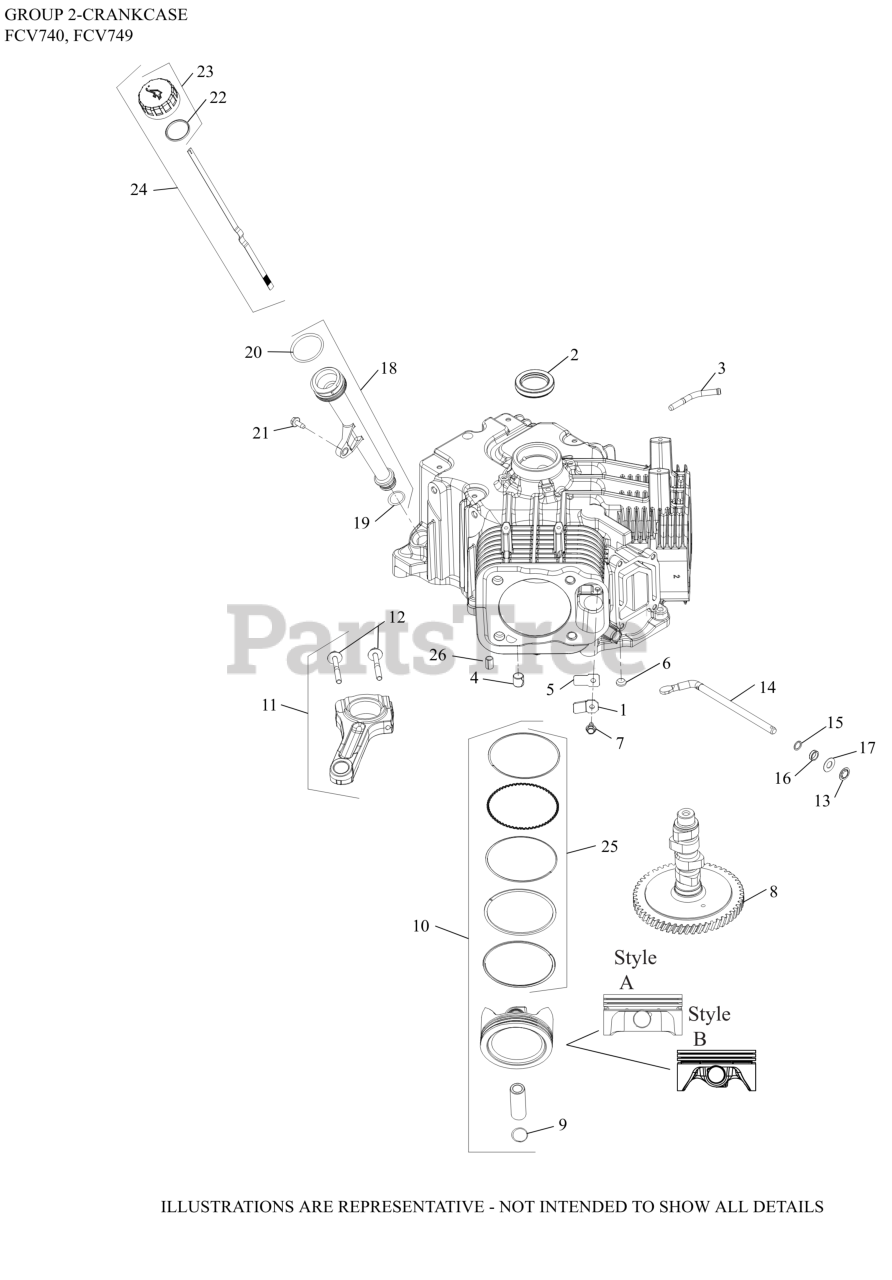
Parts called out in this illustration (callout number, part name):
1	RETAINER, BREATHER REED
2	SEAL, OIL (HELIX LIP)
4	PIN, LOCATING
5	REED, BREATHER-(#2440207S)
6	PLUG, CUP
7	SCREW, FLG THD FRM M5X.8X10
8	KIT, CAMSHAFT
9	RETAINER, PISTON PIN
10	KIT,PSTN/RNG STYLE A(STD)(#2587406S)
10	KIT,PSTN/RNG STYLE A(.08)
10	KIT,PSTN/RNG STYLE A(.25)USE 2587411-S
10	KIT,PSTN/RNG STYLE A(.50)(#2587404S)
10	KIT,PSTN/RNG STYLE B(STD)
10	KIT,PSTN/RNG STYLE B(.08)
10	KIT,PSTN/RNG STYLE B(.25)
10	KIT,PSTN/RNG STYLE B(.50)
12	KIT, ROD BOLTS-(#25086677S)
13	RETAINER, RING
14	SHAFT, GOVERNOR CROSS
15	WASHER, FLAT 11/32"
16	SEAL, GOVERNOR CROSS SHAFT
17	WASHER, FLAT 9 MM
18	TUBE ASSEMBLY
19	O-RING, LOWER OIL FILL TUBE
20	O-RING, UPPER OIL FILL TUBE
21	SCREW, FLG THD FRM M5X0.8X13
22	O-RING, DIPSTICK
23	KIT, OIL FILL CAP (YELLOW)
24	DIPSTICK, ASSY
25	RING DISC USE PISTON ASSY PER SPEC
25	RING SET(.08)STYLE A-1.5mm Tp RING THICK
25	RING SET(.25)STYLE A-1.5mm Tp RING THICK
25	RING SET(.50)STYLE A-1.5mm Tp-(#DSC)
25	RING SET(STD)STYLE B-1.2mm Tp RING THICK
25	RING SET(.08)STYLE B-1.2mm RING THICK
25	RING SET(.25)STYLE B-1.2mm Tp RING THICK
25	RING SET(.50)STYLE B-1.2mm Tp RING THICK
NI	ROD, ASSEMBLY CONNECTING
